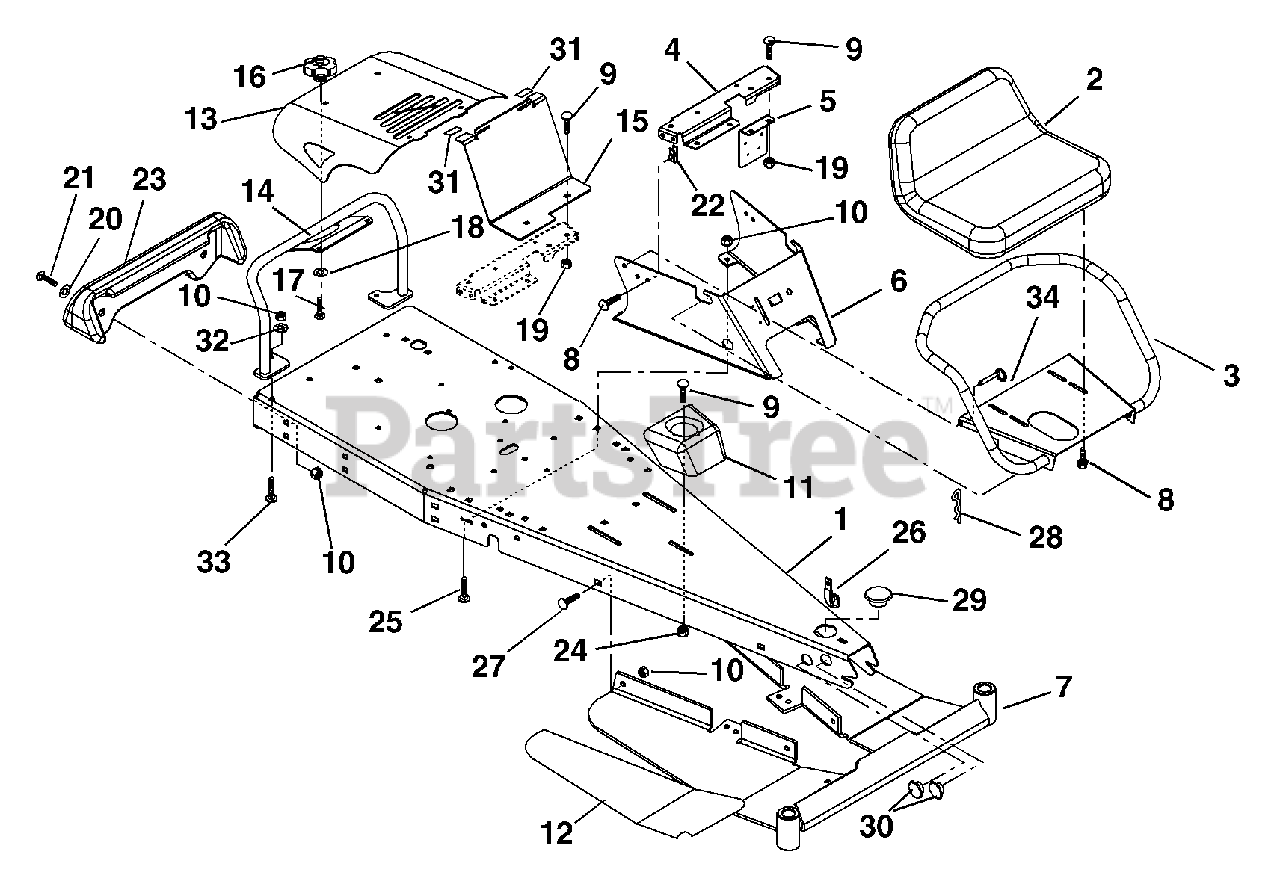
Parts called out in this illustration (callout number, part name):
2	Seat,Low Back TS2300
3	Weldment, Seat Plate and Armrest
4	Reforcement, Seat Support
5	Panel, Solenoid Mounting
6	Seat Support
7	Weldment, Footrest
8	Bolt, Serrated Hex Flange Washer Head .31-18 x 1
9	Bolt, Round Head Square Neck .31-18 x .75 Grade 5
10	Nut, Locking Top Flange .38-16
11	Cupholder
12	Grip, Rear Engine Rider Footrest Left Hand
12	Grip, Rear Engine Rider Footrest Right Hand
13	Engine, Hood (032)
14	Weldment Tube (032)
15	Bracket, Hood Support (032)
16	Knob, Clamping .31-18 Nyloc (032)
17	Bolt, Round Head Square Short Neck .31-18 x .75 Grade 5 (032)
18	Nut, Push .312 (032)
19	Nut, Locking Top Flange .31-18 (032)
20	Washer, Flat Steel .438 x 1.00 x .083
21	Bolt, Hex .38-16 x 1.75 Grade 5
22	Nut, Retainer .25-20 x .56
23	Weight, Sport Zoom
24	Nut, Spin Lock Flange .312-18
25	Bolt, Round Head Square Neck .38-16 x .75 Grade 5 (032)
26	J, Clamp
27	Bolt, Round Head Square Neck .38-16 x 1.00 Grade 5
28	Pin, Hair External .12 x .31 x 2.37
29	Hole Plug, 1.38
30	Hole Plug, 1.00
31	Tape, Foam .12 x 1.00 Vinyl
32	Retainer, .38 Push-On
33	Bolt, Round Head Square Neck .38-16 x 1.00
34	Pin, Detent with Ring .25 x 1.00
